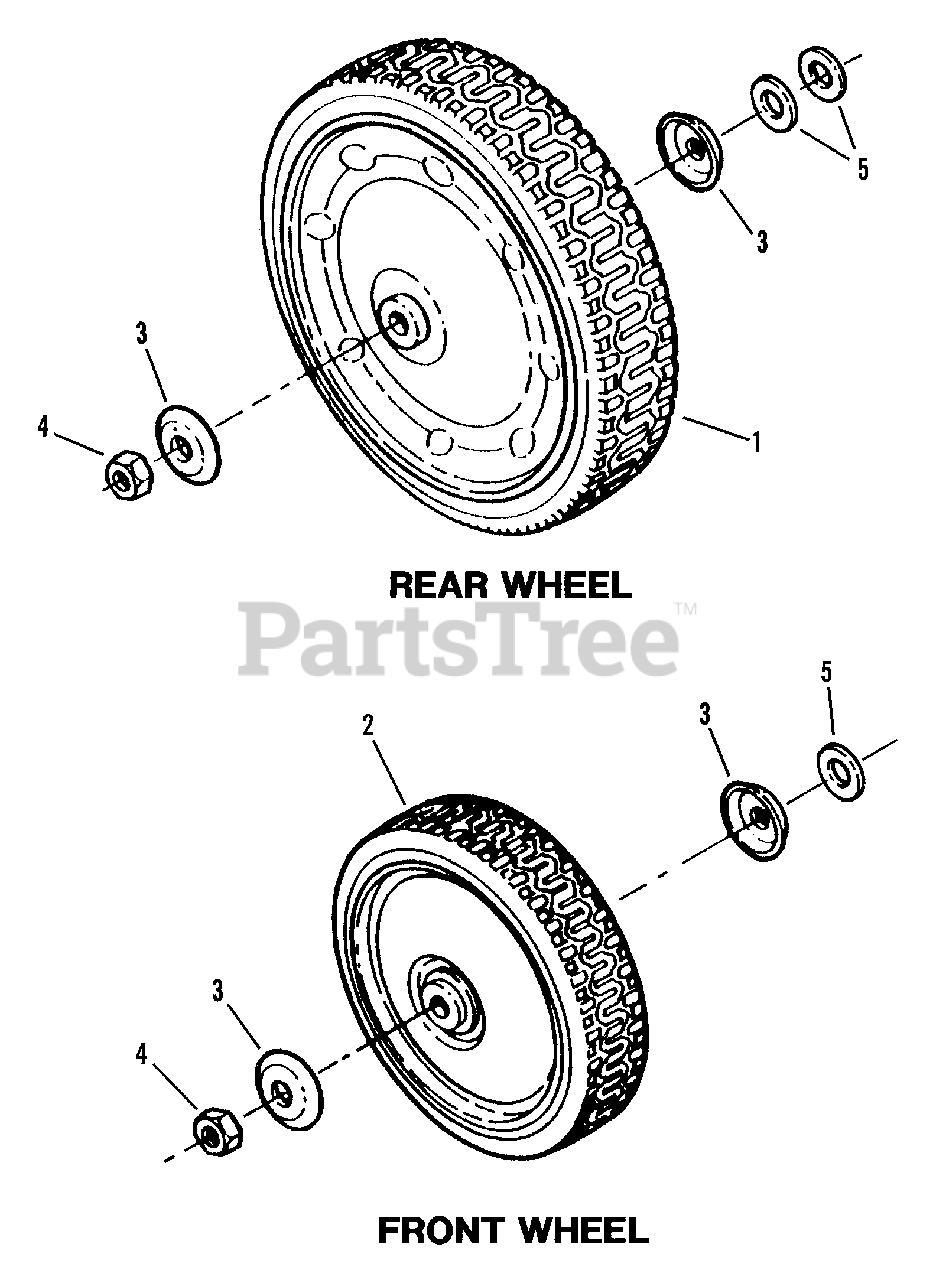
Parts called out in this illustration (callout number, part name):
1	WHEEL, Rear 9.20 x 2.00 Steel Rim (Self-Propelled Models)
2	WHEEL, Front 7.00 x 1.75 Steel Rim
3	HUB-CAP (Push Models & Front Wheels)
4	NUT, 5/16-18 Hex Center Lock
5	WASHER, 7/16 Flat
